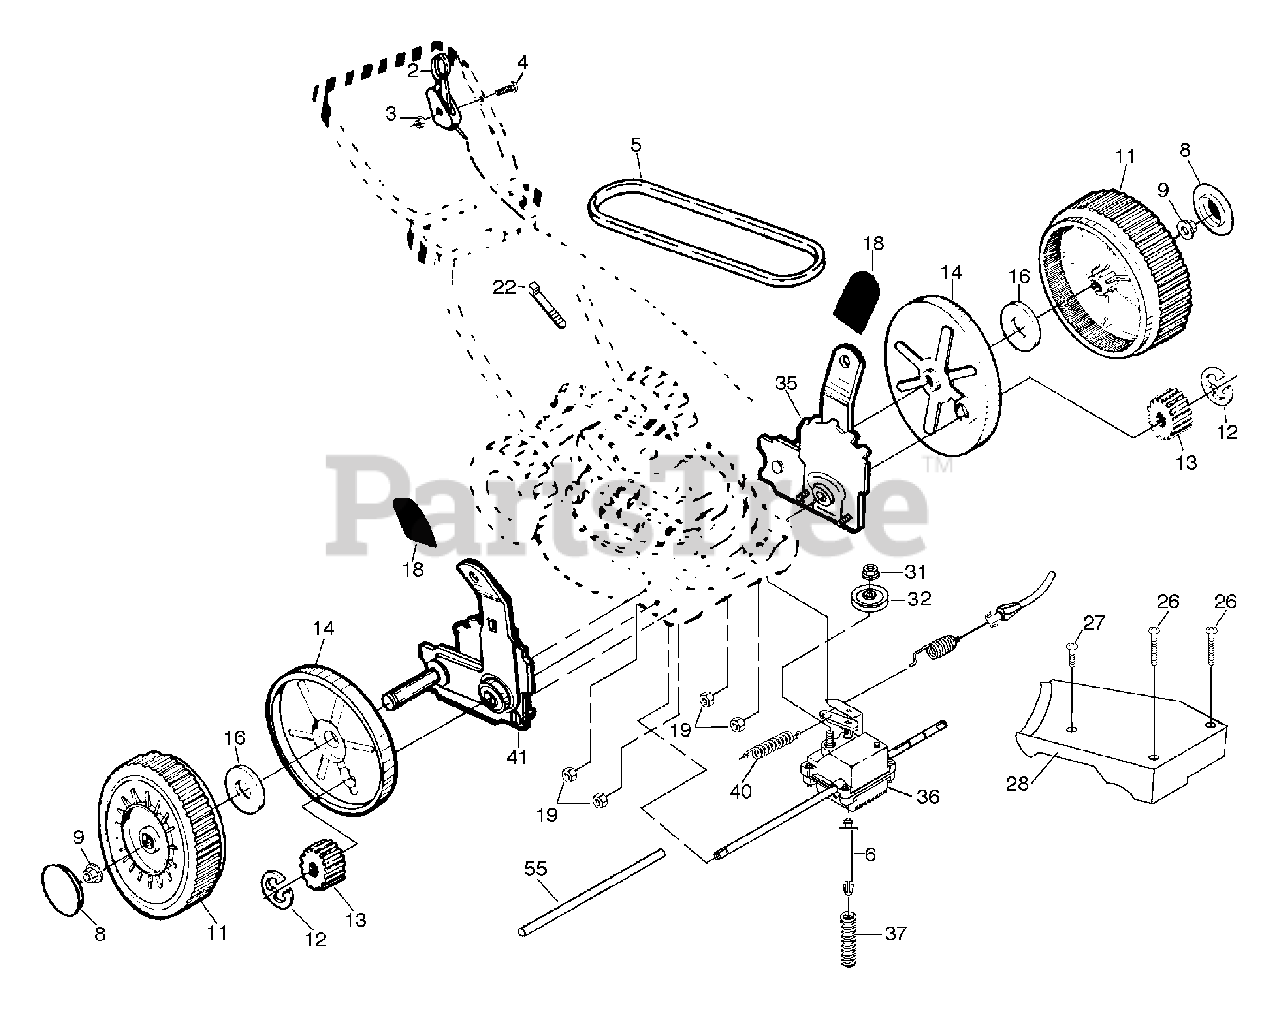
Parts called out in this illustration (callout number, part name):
2	Drive Control
3	Locknut #10-24
4	Hex Washer Head Screw 1/4-20 x 2.12
5	V-Belt
6	Spring Retainer
9	Flanged Locknut 3/8-16
11	Wheel & Tire Assembly
14	Dust Cover
16	Washer 1/2 x 1-1/2 x .134
18	Selector Knob
19	Hex Locknut 1/4-20
22	Wire Tie
26	Pan Head Tapping Screw #10-24 x 2-3/4
27	Hex Head Tapping Screw #10
28	Drive Cover
31	Hex Flange Nut
32	Drive Pulley
35	Wheel Adjuster Assembly (Left)
36	Gear Case Assembly
41	Wheel Adjuster Assembly (Right)
55	Driveshaft Cover
